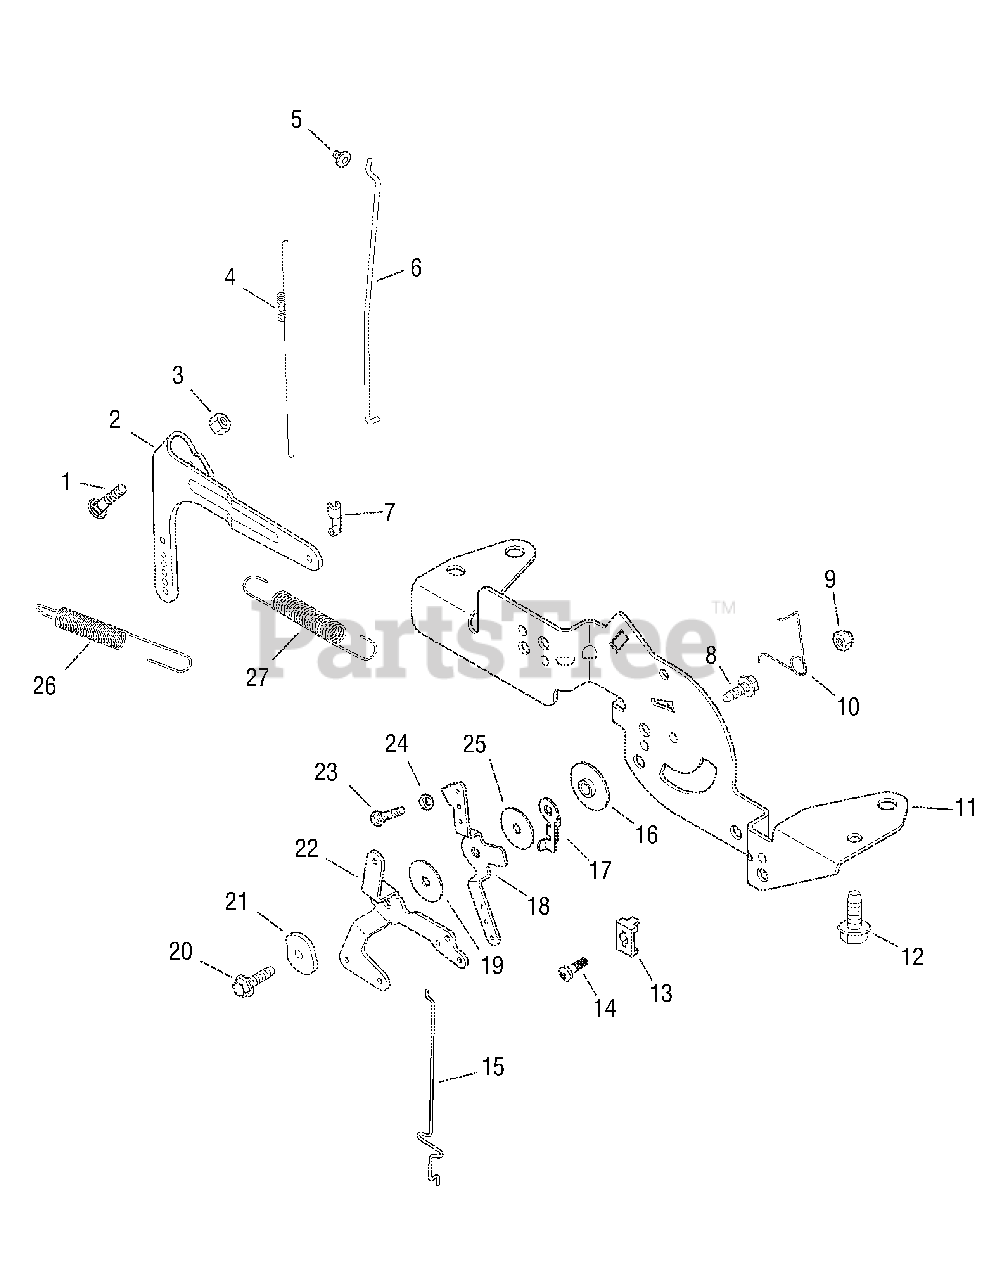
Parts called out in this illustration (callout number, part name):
1	Bolt, round head square neck
2	Lever, governor
3	Nut, hex. flange M6x1.0
4	Spring, linkage
5	Bushing, linkage retaining
6	Linkage, throttle
7	Bushing, throttle linkage
8	Screw, hex. flange M5x0.8x16
9	Nut, hex. lock M5x0.8
10	Spring, choke return
11	Bracket, control
12	Screw, hex. flange M6x1.0x16
13	Clamp, dual conduit
14	Screw, thread forming
15	Linkage, choke
16	Spacer, control assembly
17	Lever, throttle actuator
18	Lever, throttle control
19	Washer, plain 5.5 mm
20	Screw, hex. flange M5x0.8x20
21	Washer, spring 1/4"
22	Lever, choke
23	Screw, hex. head cap M4x0.7x25
24	Nut, hex. M4x0.7
25	Washer, plain
26	Spring, governor
27	Spring, governor
